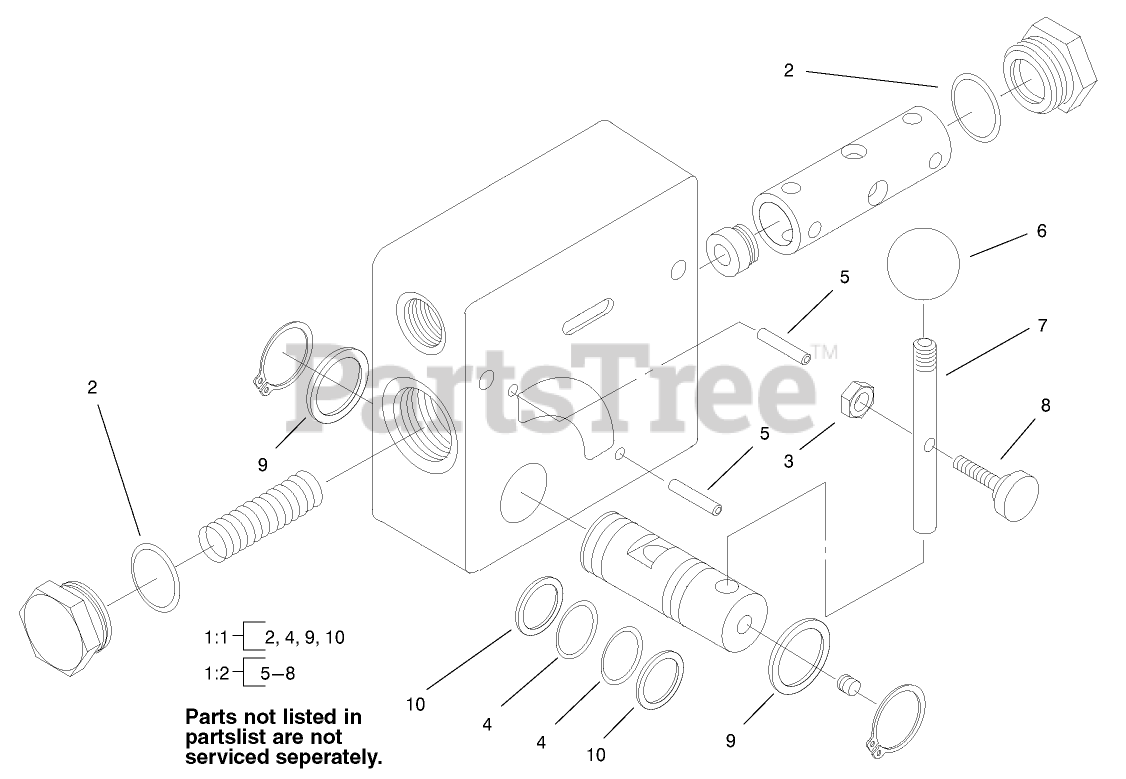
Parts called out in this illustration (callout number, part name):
1	Valve-Flow, Hydraulic
1:1	SEAL KIT
1:2	HANDLE HARDWARE KIT
3	NUT-LOCK, NI
